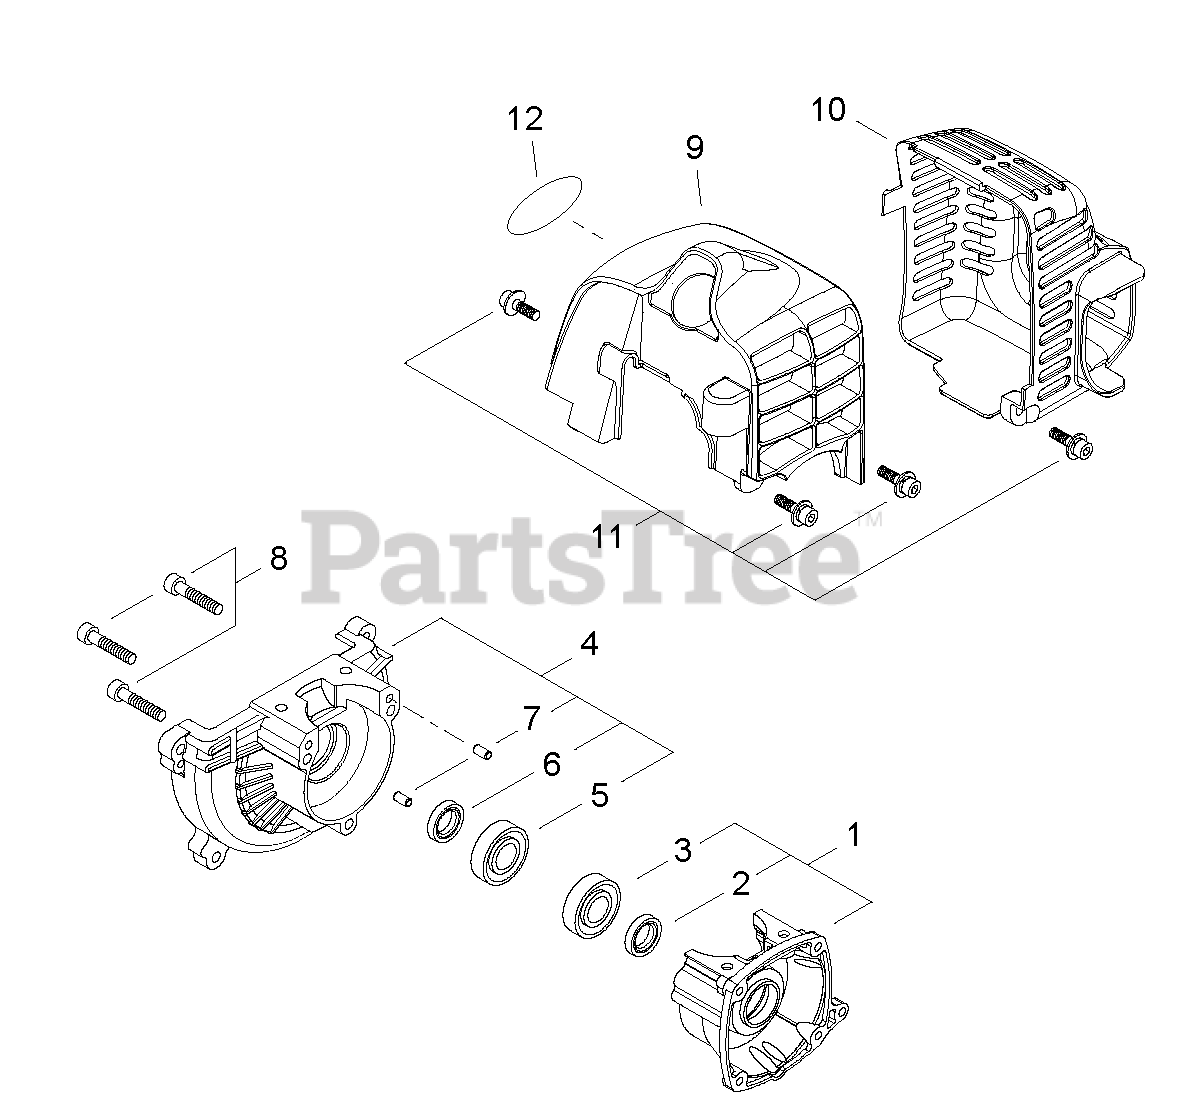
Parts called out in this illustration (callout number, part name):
1	CRANKCASE ASSY - REAR
2	SEAL, OIL - 12
3	BEARING, BALL - 6001C3
4	CRANKCASE ASSY - FRONT
5	BEARING, BALL - 6001C3
6	SEAL, OIL - 12
7	PIN - LOCATING
8	SCREW - 5X25
9	COVER, ENGINE
10	COVER, MUFFLER
11	SCREW - 4X16
12	LABEL - HOME PRO ID
